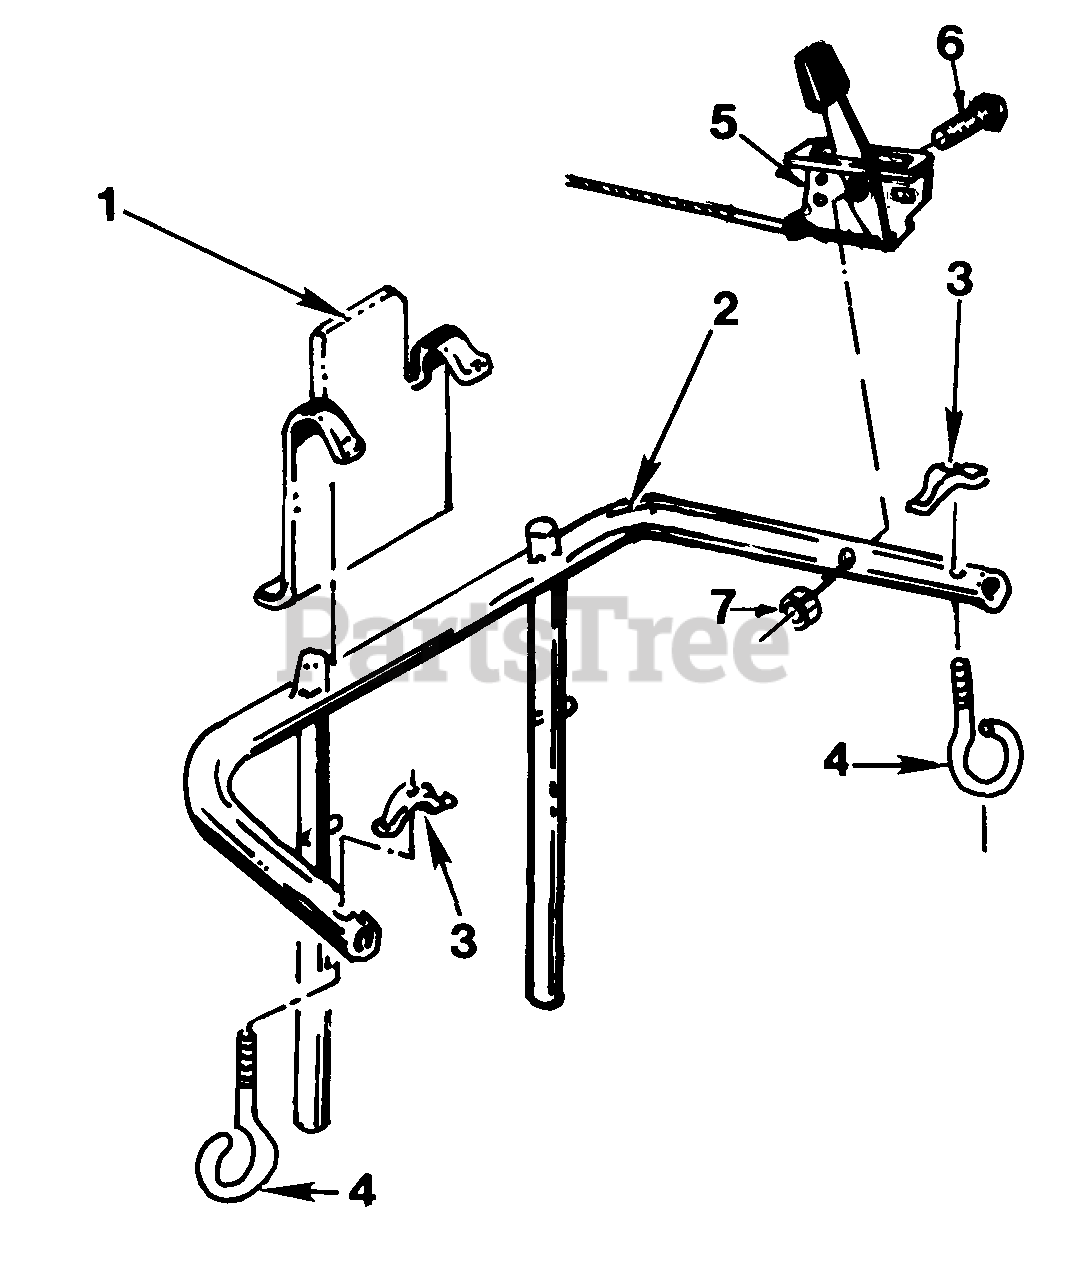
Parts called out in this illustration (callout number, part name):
1	Heat Shield
2	Chain Arm Structure
3	Chain Adjusting Nut
4	Chain Hook
5	Control, Throttle
6	Capscrew, 1/4F x 1-1/2
7	Locknut, 1/4F
